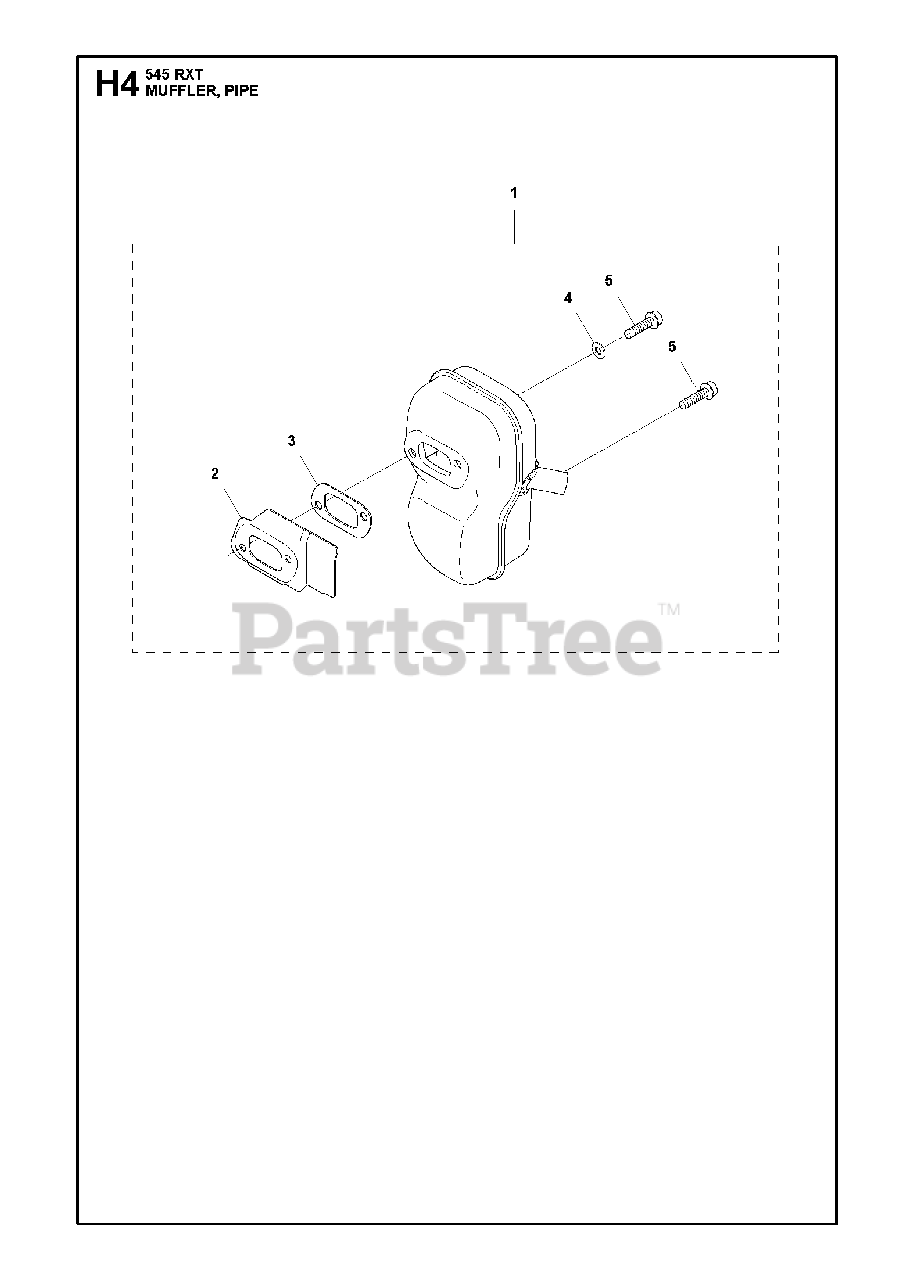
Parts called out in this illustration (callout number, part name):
1	MUFFLER ASSY
2	HEAT DEFLECTOR
4	DOUBLE WASHER
